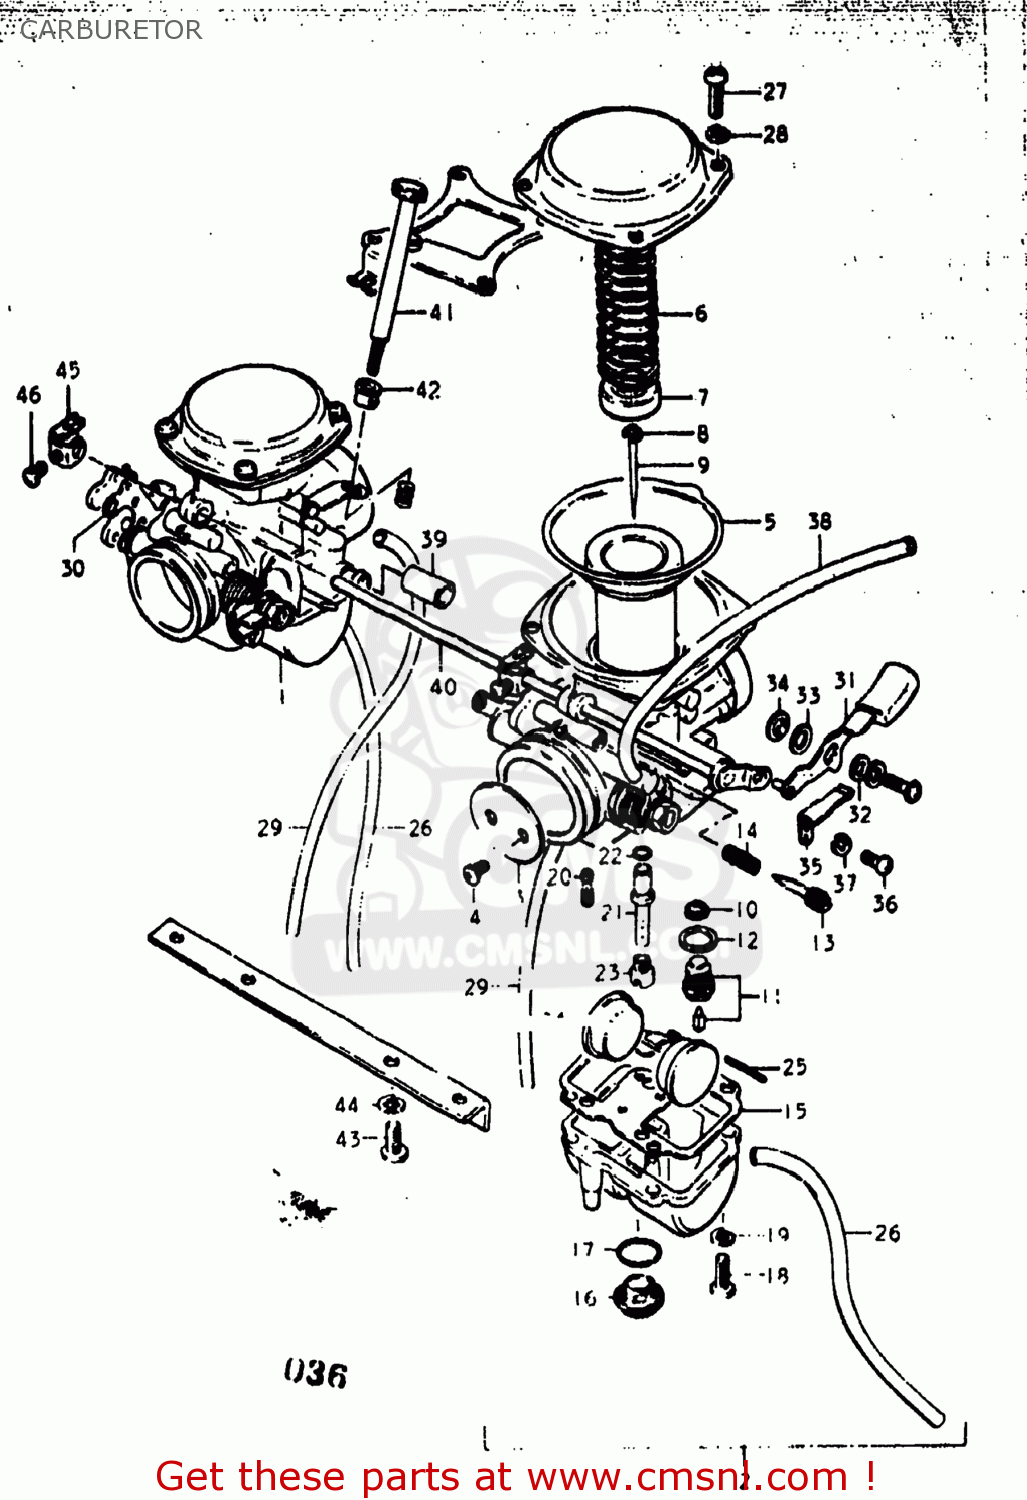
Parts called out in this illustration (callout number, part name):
1	CARBURETOR ASSEMBLY
2	CARBURETOR ASSEMBLY
3	VALVE,THROTTLE
4	SCREW
5	DIAPHRAGM ASSY
6	SPRING,DIAPHRAGM
7	CONNECTOR
8	CLIP
9	NEEDLE,JET
10	FILTER
11	VALVE ASSY,NEEDLE
12	GASKET,MAIN JET HOLDER (NAS)
13	SCREW,PILOT AIR
14	SPRING
15	GASKET,FLOAT CAHMBER (NAS)
16	SCREW,GUIDE
17	O-RING
18	SCREW
19	LOCK WASHER
20	JET,PILOT
21	JET,NEEDLE
22	O-RING
23	JET,MAIN(112.5)
24	FLOAT
25	PIN,FLOAT
26	HOSE
27	SCREW
28	LOCK WASHER
29	HOSE
30	GASKET
31	LEVER
32	WASHER,STARTER LEVER
33	WASHER,STARTER LEVER
34	RING,STARTER LEVER
35	SPRING
36	SCREW
37	LOCK WASHER
38	HOSE
39	HOSE
40	SHAFT,STARTER
41	ADJUSTER
42	BUSH
43	SCREW 6X12
44	LOCK WASHER
45	LEVER, STARTER
46	SCREW
